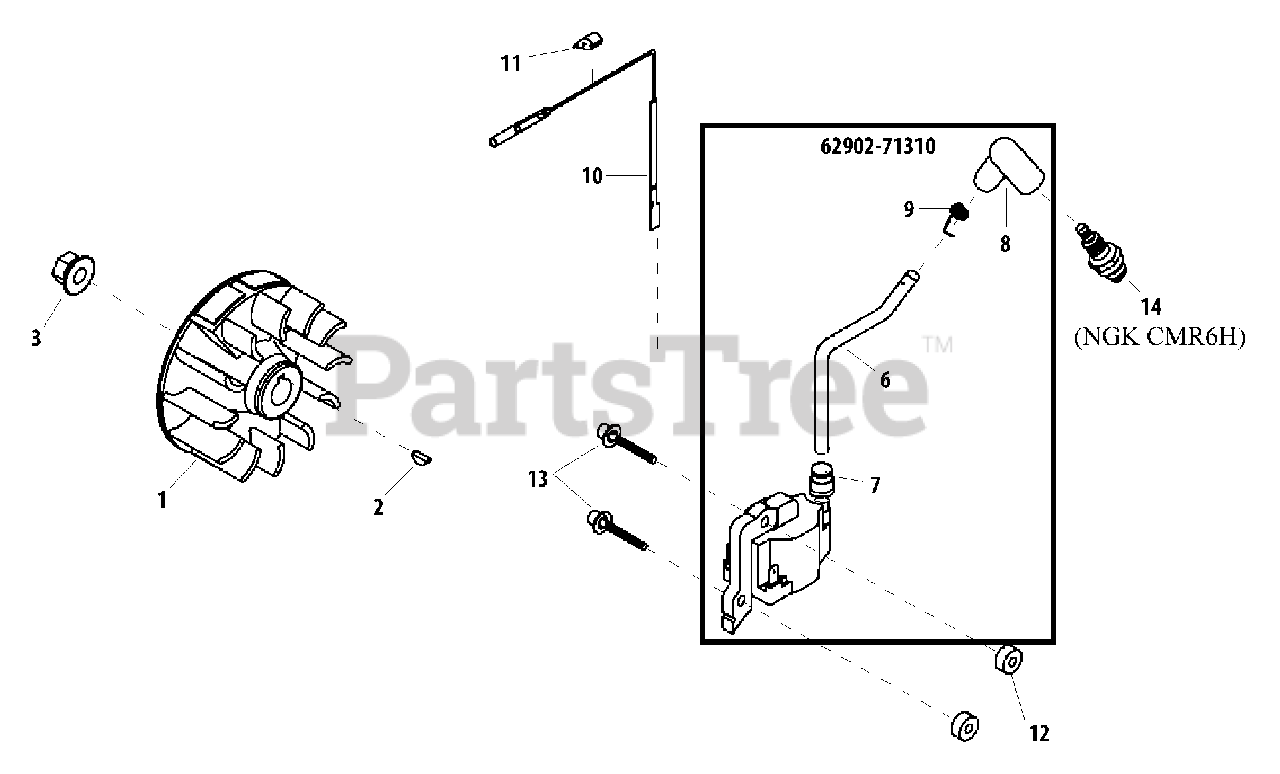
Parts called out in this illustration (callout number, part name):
1	FLYWHEEL
2	KEY - 3X10
3	NUT - 8
7	GROMMET
8	CAP, SPARK PLUG
9	TERMINAL, SPARK PLUG CAP
10	LEAD - IGNITION
11	GROMMET
12	INSULATOR
13	SCREW - 4X26
14	SPARK PLUG -- CMR-6H
62902-71310	IGNITION COIL ASSY
